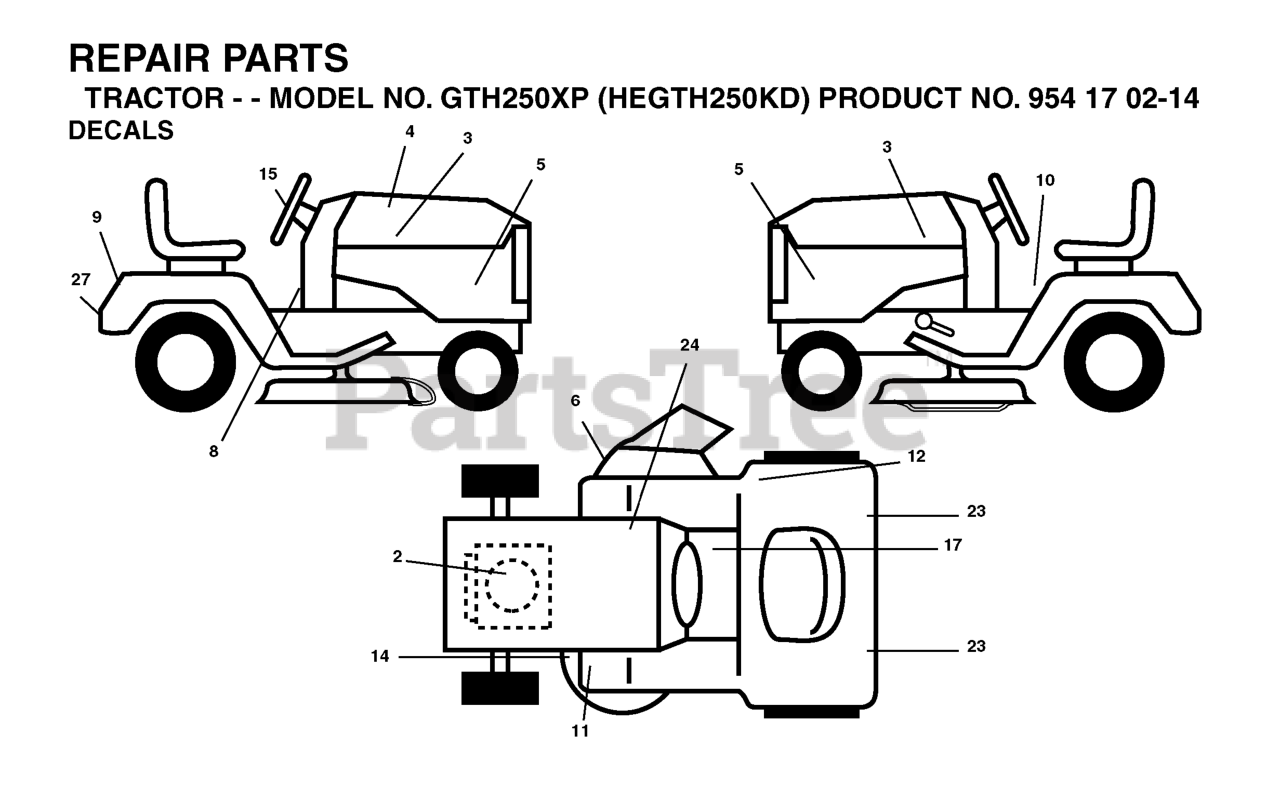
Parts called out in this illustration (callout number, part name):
3	DECAL.HOOD.HUSQVARNA.INTERNATI
6	DECAL.INTERNATIONL.CUTFINGER
8	Decal, Dash
10	DECAL READ OWNER'S MAN SYMS
11	Decal, Foot Rest
12	DECAL.FENDER
14	DECAL V-BELT SCHEMATIC
15	DECAL.STEERING.HUSQ.BLUE
17	DECAL PARK BRAKE
23	REFLECTOR-TAIL YT
24	DECAL BTRY SYMBOLS
27	DECAL.BYPASS.FENDER.CRD.LT.YT
